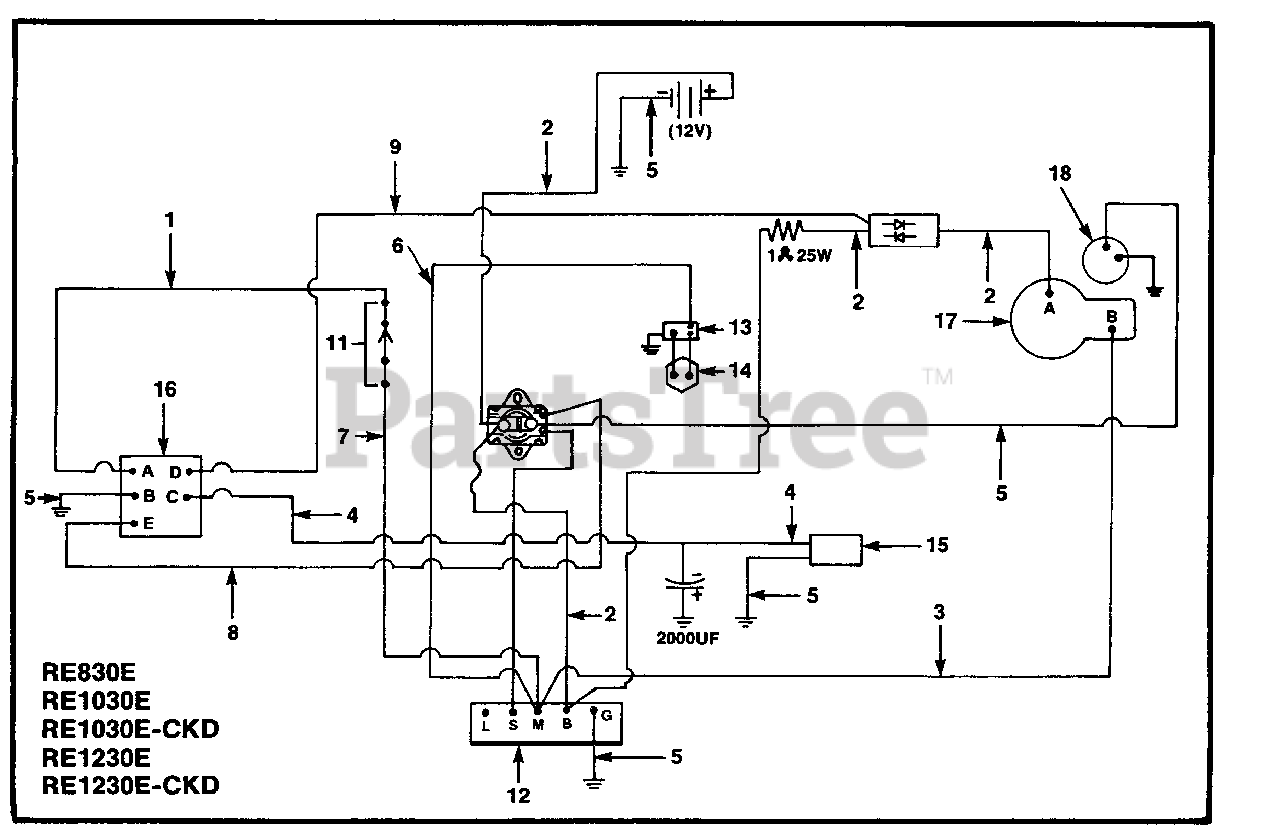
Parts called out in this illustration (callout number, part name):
1	White/Yellow Stripe
2	Red
3	Brown
4	Blue
5	Black
6	Violet
7	Yellow
8	Green
9	Orange
11	Seat Switch
12	Ignition Switch
13	Safety Module
14	Neutral Switch
15	PTO Clutch
16	PTO Switch
17	Engine
18	Starter
A	Alternator
B	Magneto
